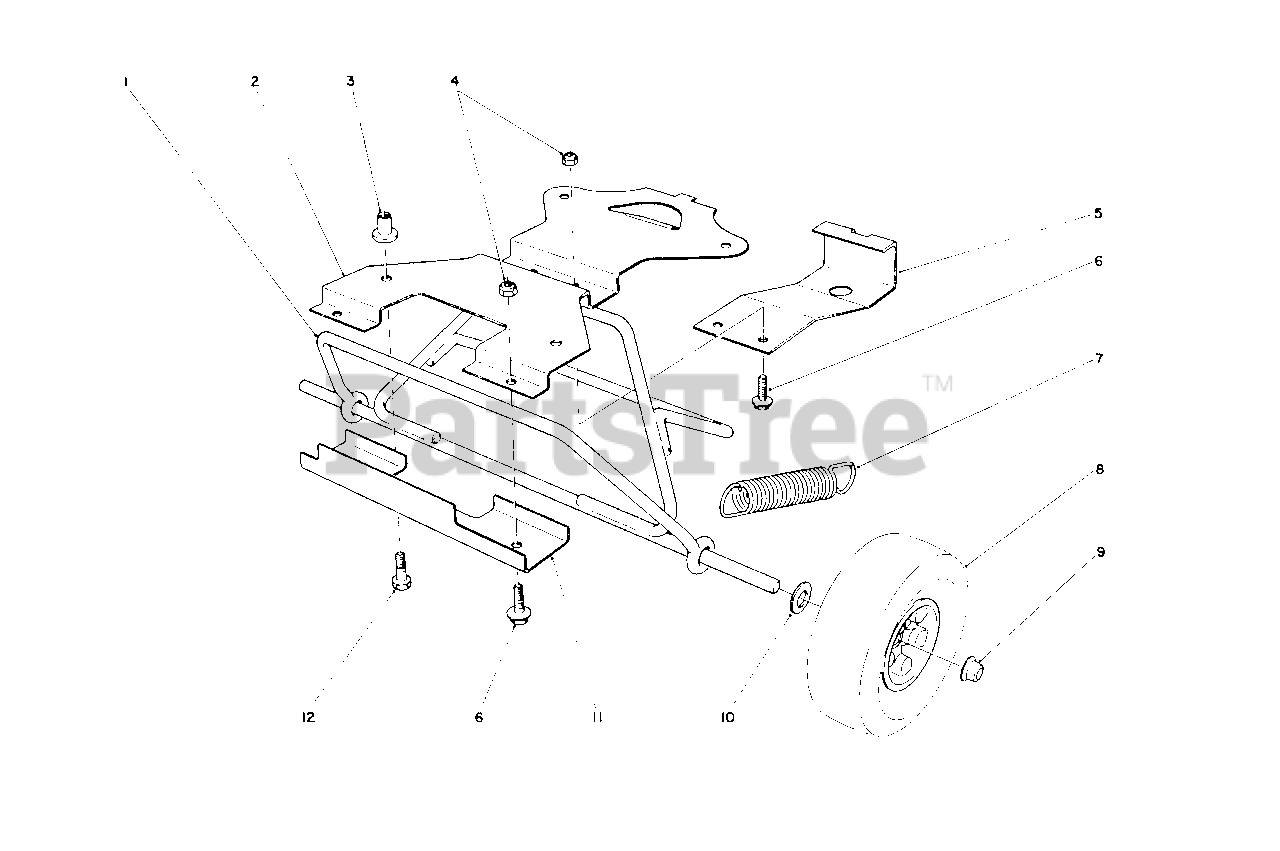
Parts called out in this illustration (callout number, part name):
1	Axle Assembly
2	Plate-Wheel
4	Nut-Lock
6	Screw-Hex Washer Hd.
7	Spring-Extension
8	Wheel Assembly
9	Nut-Push
10	Washer-Flat
11	Retainer-Axle
12	Screw-Mounting
